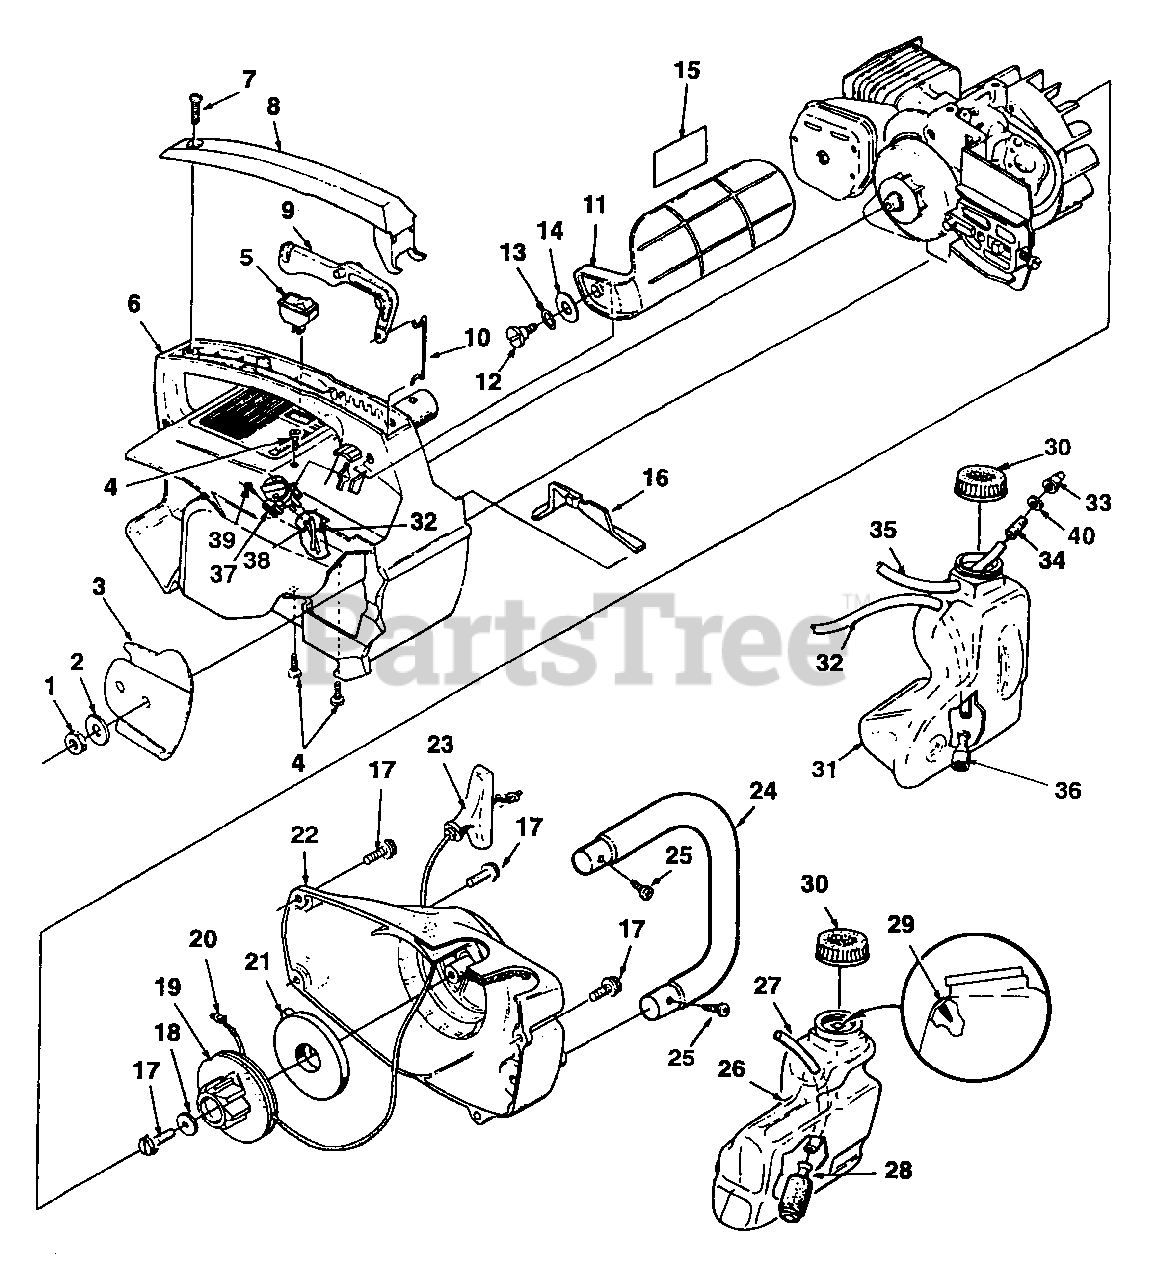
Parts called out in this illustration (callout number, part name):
1	NUT-Guide Bar
2	WASHER-Flat
3	PLATE-Guide Bar
4	SCREW-Pan Hd. (10-24 X 3/4")
5	SWITCH-Rocker
6	HOUSING-Engine
7	SCREW-Pan Hd. (#10 X 5/8")
8	COVER-Handle
9	TRIGGER
10	ROD-Throttle
11	HANDGUARD
12	SCREW-Shoulder (#10 X .560)
13	WASHER-Curved Spring
14	WASHER-Flat
15	DECAL-Handguard
16	COVER-Air Filter
17	SCREW-Thd. Form. (10-24 X 3/4")
18	WASHER-Retaining
19	PULLEY-Starter
20	ROPE-Starter
21	SPRING-Rewind
22	HOUSING-Rewind Starter w/Decals
23	GRIP-Starter
24	HANDLE BAR
25	SCREW-Pan Hd. (10-26 X 3/4")
26	FUEL TANK
27	TUBING-Rubber (7")
28	FILTER-Fuel
29	VALVE-Duck Bill
30	FUEL CAP
31	OIL TANK
32	TUBING-Rubber (8")
33	VALVE-Duck Bill
34	CONNECTOR-Oil Line
35	TUBING-Rubber (2 1/2")
36	FILTER-Oil
37	OIL VALVE
38	TUBING-Rubber (4 1/4")
39	SCREW-Thd. Form. Pan, #8
40	WASHER-Lock (#6)
